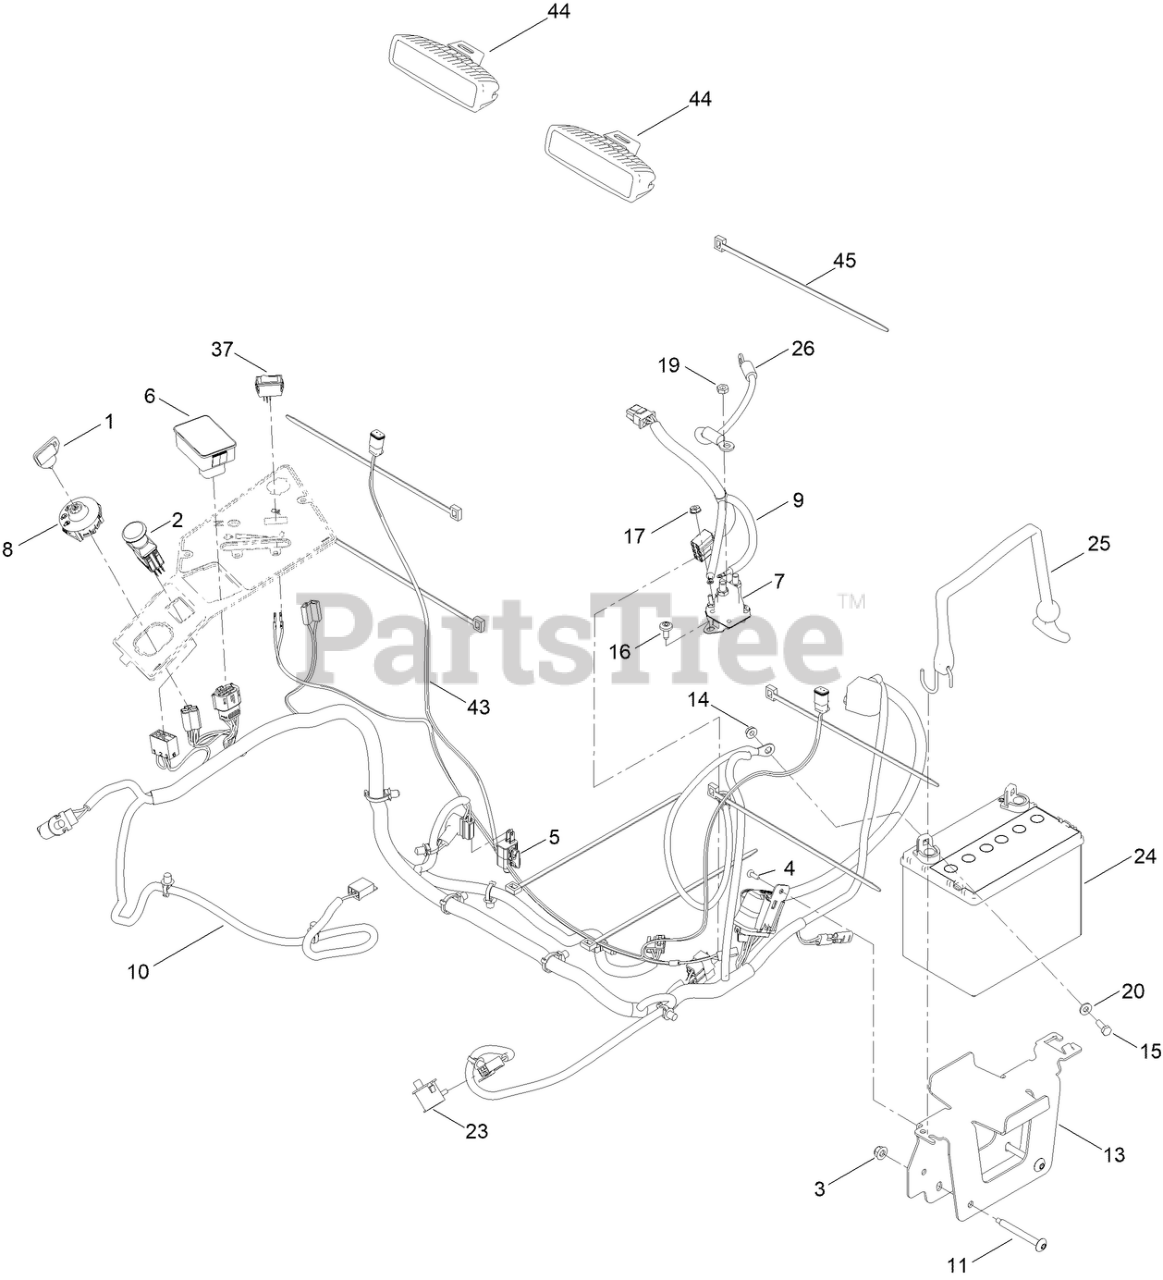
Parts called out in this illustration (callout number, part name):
1	KEY-IGNITION
2	SWITCH-PTO
3	NUT-HF, NI
4	SCREW-FORMING, THREAD
5	SWITCH
6	MODULE ASM
7	SOLENOID
8	SWITCH-IGNITION
9	ADAPTER-HARNESS, WIRE
10	HARNESS-WIRE
11	SCREW-TORX
13	TRAY-BATTERY
14	NUT-HF
15	SCREW-HH
16	SCREW-TORX
17	NUT-KEPS
19	NUT-JAM
20	WASHER-FLAT
23	SWITCH-BAIL
24	BATTERY - WET (300 CCA, 12 V)
25	STRAP, BUNGEE
26	CABLE-BATTERY, POSITIVE
37	SWITCH-ROCKER
43	HARNESS-WIRE, LIGHT KIT
44	LIGHT-LED
45	TIE-PLASTIC
